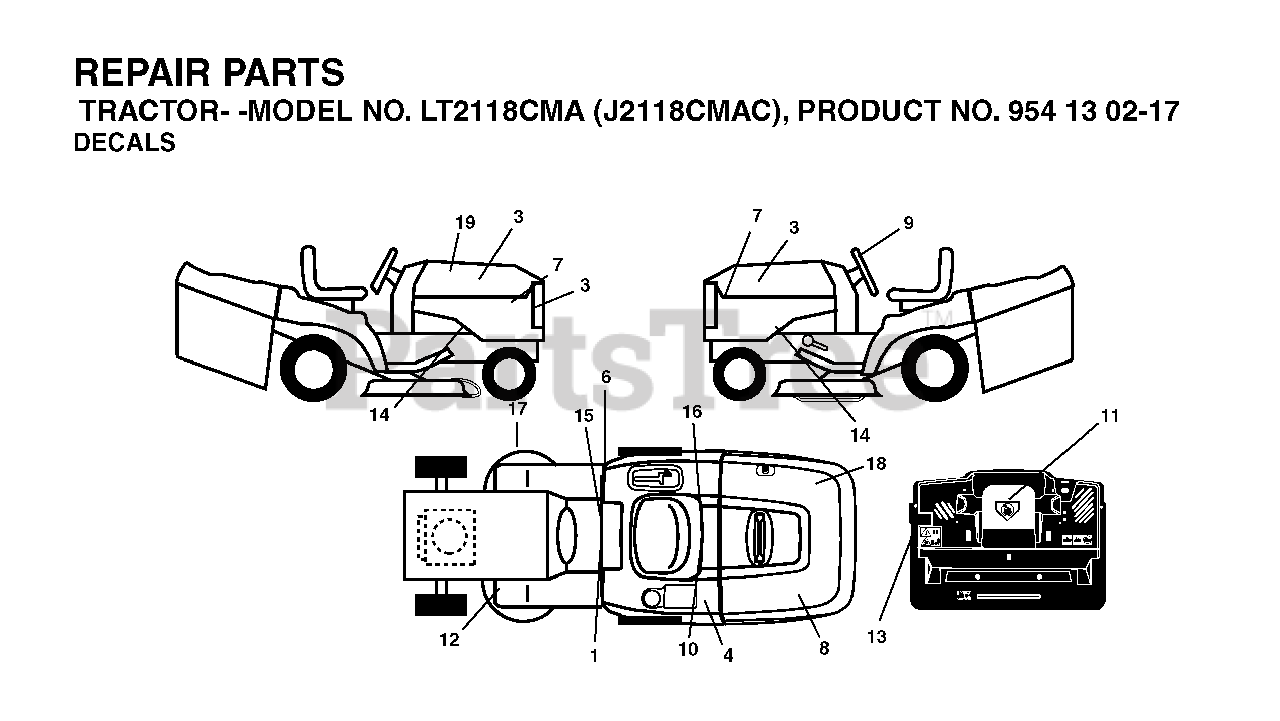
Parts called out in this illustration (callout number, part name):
1	DECAL READ OWNER'S MAN SYMS
10	DECAL BTRY SYMBOLS
11	DECAL.INTERNATIONL.CUTFINGER
15	DECAL PARK BRAKE
16	DECAL.BYPASS.FENDER.CRD.LT.YT
